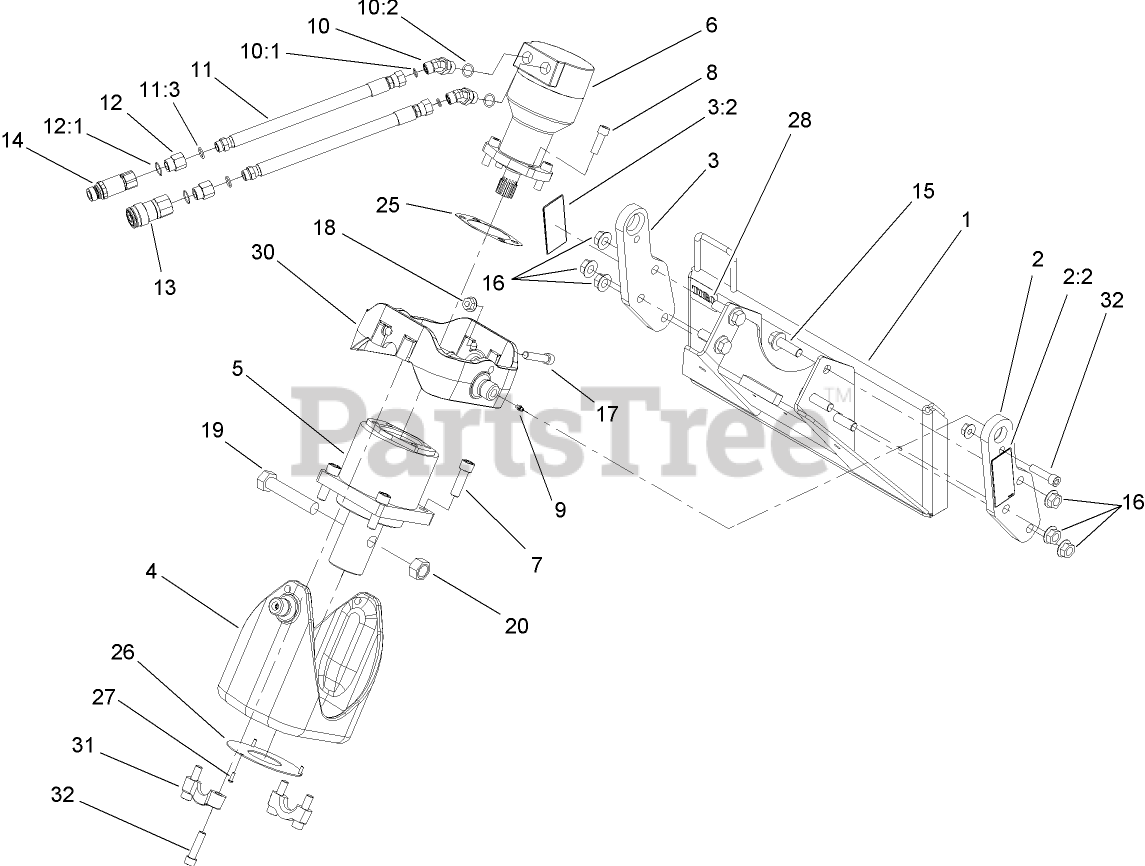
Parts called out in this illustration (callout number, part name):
1	AUGER MOUNT ASM
2	PLATE-PIVOT, LH
2:2	DECAL-DANGER
3	PLATE-PIVOT, RH
3:2	DECAL-DANGER
4	YOKE-AUGERHEAD
5	PLANETARY DRIVE ASM
6	HYD MOTOR ASM
7	SCREW-HSH
8	SCREW-HSH
9	FITTING-GREASE
10	FITTING-HYD, 45 DEG
10:1	O-RING
10:2	O-RING
11	HYD HOSE ASM
11:3	O-RING
12	ADAPTER-HYD
12:1	O-RING
13	COUPLER-FACE, FLUSH
14	NIPPLE-CONNECT, PRESSURE
16	NUT-FLANGE
17	SCREW-HSH
18	NUT-HHF
19	SCREW
20	NUT-HEX
25	GASKET
26	PLATE-GUARD, SEAL
27	SCREW-HSBH
28	DECAL
30	SWIVEL-AUGERHEAD
31	LUG-SWIVEL
32	SCREW-HSH
